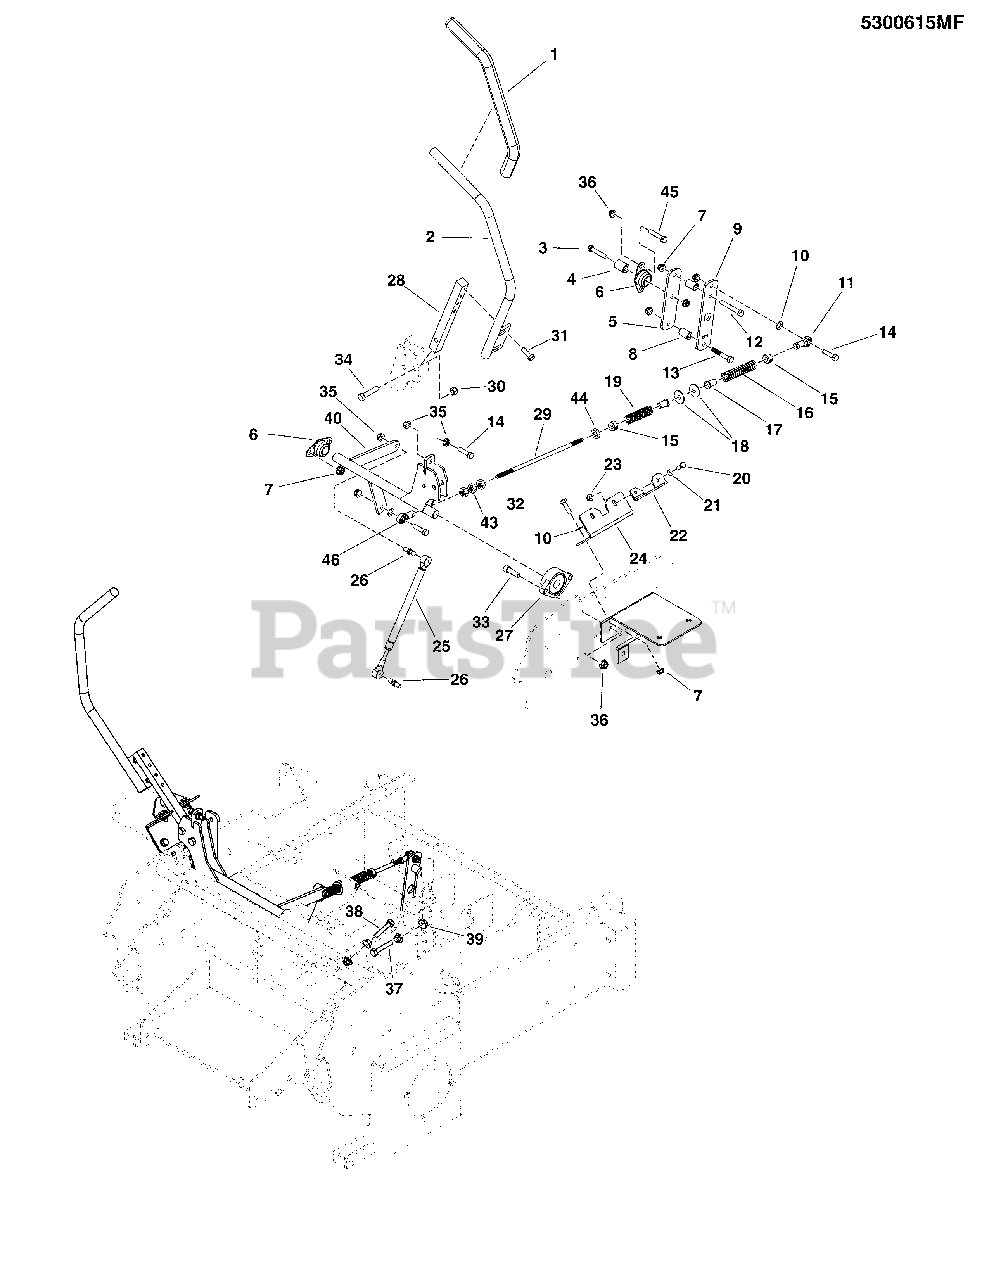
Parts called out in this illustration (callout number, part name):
1	GRIP, FOAM, 3/4 ID, 16 LONG
2	WELD, HANDLEBAR - LH - RED
3	BOLT, 5/16-18 X 1-3/4 GD5 YZ
4	SPACER, .32 X .75 X 1.06
5	BAR, PUMP LINK - INNER - RED
6	BEARING, BRONZE FLANGE, 3/4
7	NUT, 5/16-18 HEX NYLOCK FLANGE
8	SPACER, .33 X .63 X 1.00, YZ
9	BAR, PUMP LINK - OUTER - RED
10	WASHER, 5/16 SAE
11	BALL JOINT 5/16-24 LH FEMALE BRONZE RACE
12	BOLT, 5/16-18 X 2-1/4 GD5 YZ
13	BOLT, 5/16-18 X 2, GD5
14	BOLT, 5/16-18 X 1-1/4 GD5 YZ
15	COLLAR, 5/16 SET
16	SPRING, REVERSE RETURN
17	BUSHING, NYLON
18	WASHER, 5/16 FENDER
19	SPRING, COMPRESSION
20	BOLT,1/4-20X5/8
21	WASHER, 1/4 SAE
22	BRACKET, SWITCH MOUNT - RED
23	NUT, 1/4-20 HEX SERR. FLANGE
24	PLATE, NEUTRAL LOCK - RED
25	DAMPENER, CONTROL,#(P6709/P3610)
26	BALL STUD, 5/16 X .50,# PC-477-2)
27	BEARING, FLANGE
28	MOUNT, CONTROL ARM - BLK
29	ROD, HYDRO CONTROL, OUTFRONT
30	NUT, 3/8-16 HEX NYLON LOCK
31	SCREW, 5/16-18 X .750, Washer Head Taptite
32	BOLT, 5/16-18 X 3/4 GD5 YZ
33	BOLT, 3/8-16 X 1-1/4 SHCS
34	BOLT, 3/8-16 X 1-3/4 GD5
35	NUT, 5/16-18 HEX SERRATED FLANGE (SMALL)
36	NUT, 3/8-16 HEX NYLOCK FLANGE
37	BOLT, 5/16-18 X 1-1/2 GD5 TFL
38	BOLT- 5/16-18 X 1-3/4 GD5 TFL
39	NUT, 5/16-18 HEX SERRATED FLANGE (LARGE)
40	WELD, MOTION CONTROL SHAFT - LH - RED
43	NUT, 5/16-24 HEX
44	NUT, 5/16-24 HEX, LH
45	BOLT, 3/8-16 X 3/4 GD5 YZ
46	BALL JOINT 5/16-24 RH FEMALE BRONZE RACE
